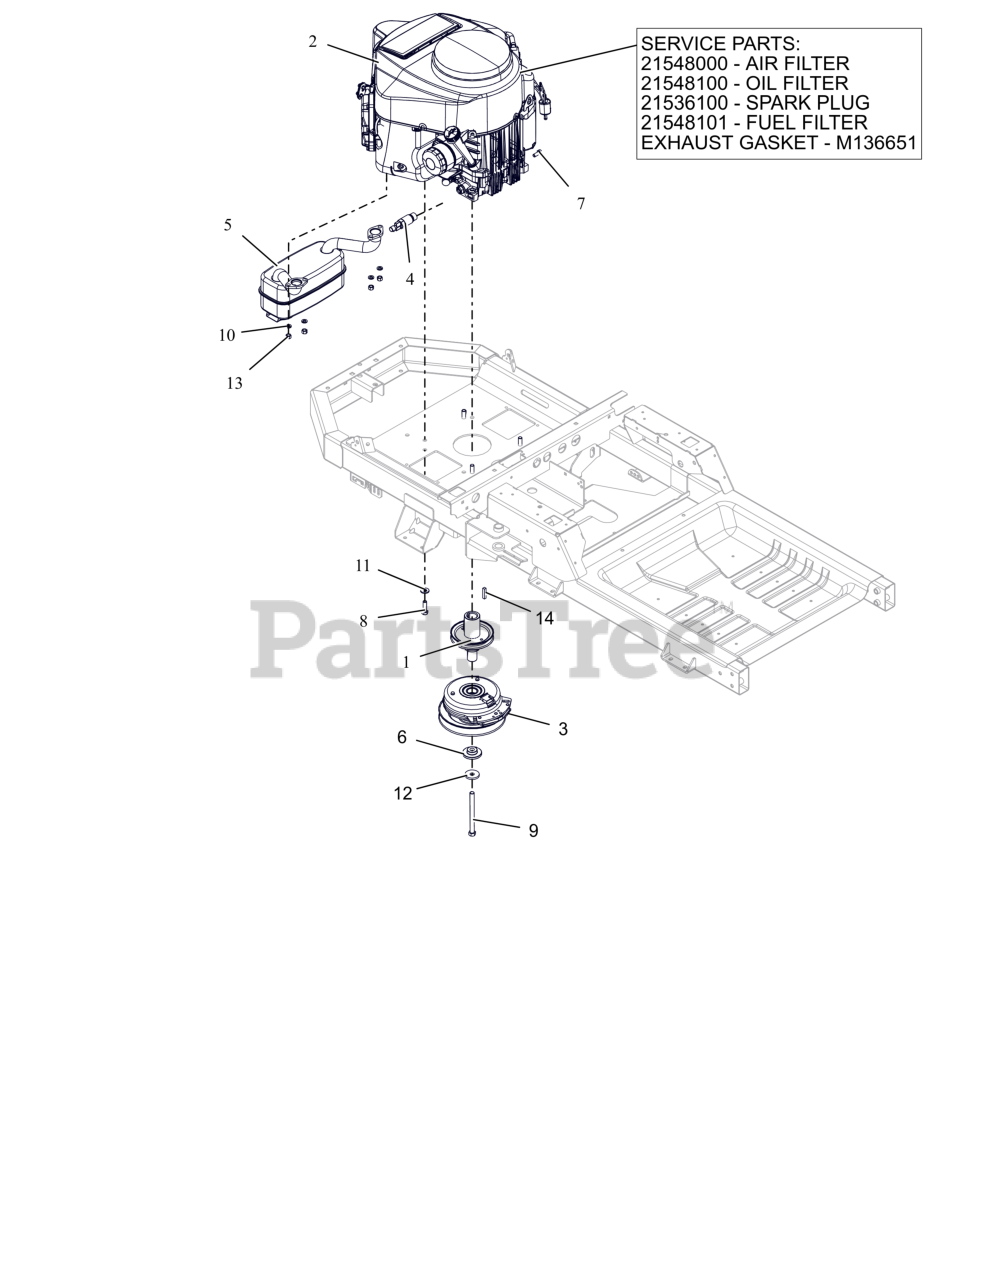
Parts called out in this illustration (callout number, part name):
1	WLDMT, DRIVE SHEAVE (LG XL)CZC
2	ENGINE, KAWASAKI FR651V 21.5HP
2	AIR FILTER, KAWASAKI FR
2	OIL FILTER, KAWASAKI FR
2	PLUG, SPARK
2	FUEL FILTER-KAWASAKI FR
2	GASKET, MUFFLER #
3	CLUTCH,105FTLB MONOPOLE 6.83"
4	DRAIN, OIL M20X2.5
5	MUFFLER - KAWASAKI
6	BSHG-FLG .469X1.06X.574X2.0
7	BLT, HEX M8-1.25X20 G8.8 ZCC
8	BLT, HEX .38-16X1.25 G5 ZCC NT
9	BLT, HEX .44-20X5.00 G8 ZCC NT
10	WSHR,LK-REG .312X.078 ZCC
11	WASHER, 3/8" SPRING DISC
12	WASHER, 7/16" SPRING DISK
13	NUT, HEX M8-1.25 G8.8 ZCC
14	KEY-SQ .25 X 1.25 X .25 SAE
